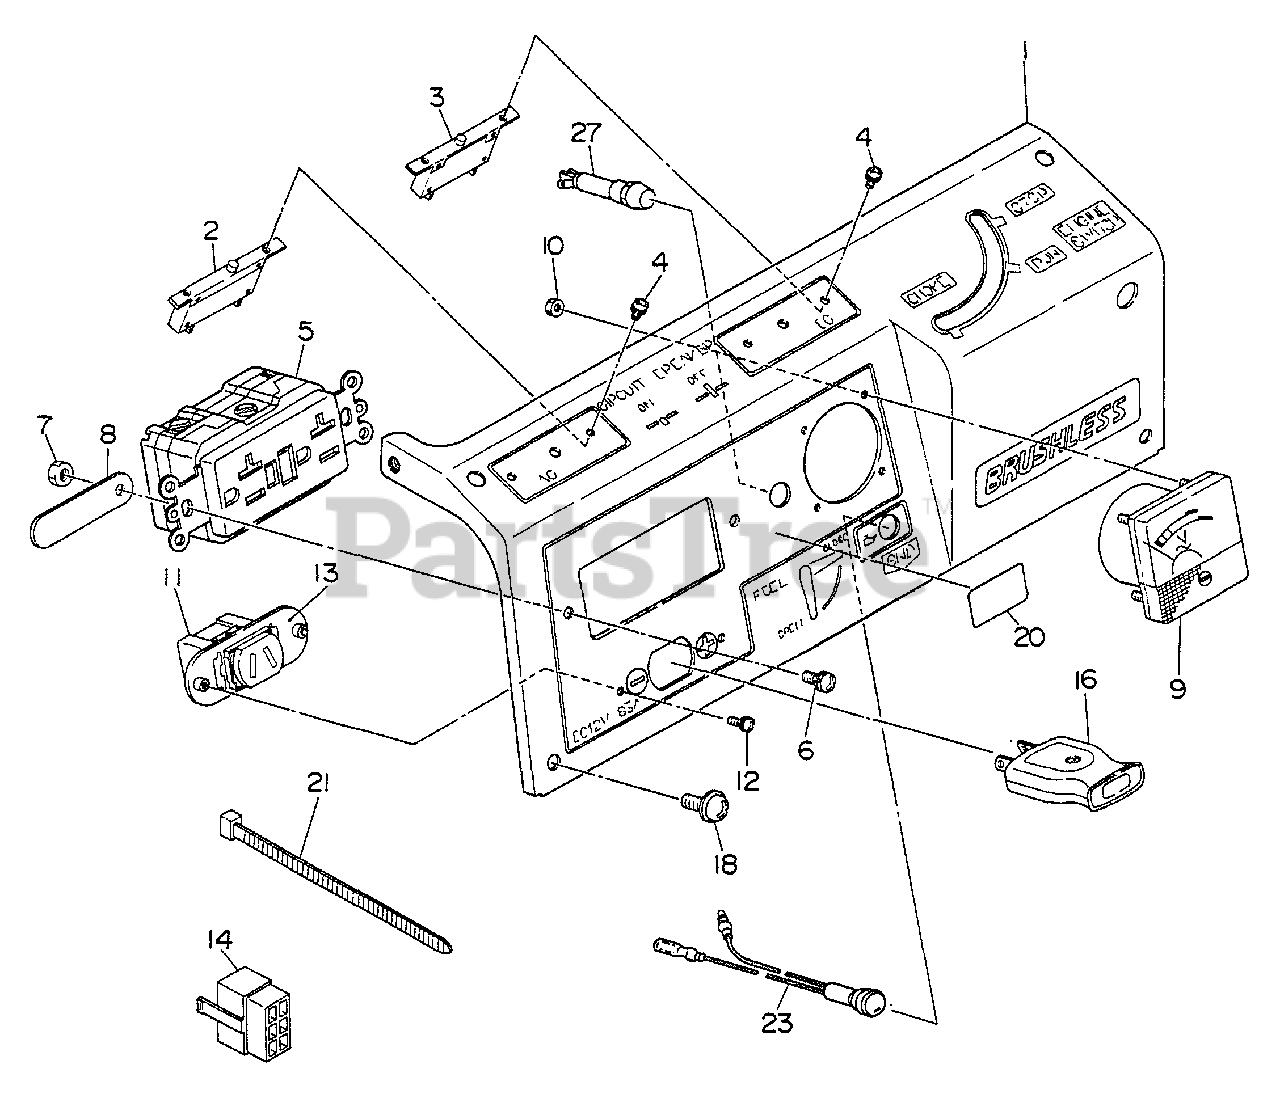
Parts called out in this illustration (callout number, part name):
1	CONTROL PANEL ASSY
2	CIRCUIT BREAKER
3	CIRCUIT BREAKER - 10A DC
4	SCREW
5	AC RECEPTACLE
6	SCREW
7	NUT
8	CLAMP
9	AC VOLT METER
10	NUT
11	DC RECEPTACLE -- 250V-10A
12	SCREW
13	DC RECEPTACLE BASE
14	CONNECTOR
18	SCREW
20	LABEL -- HZ-V
21	TIE, CABLE
23	LED LAMP ASSY
27	LAMP, NEON
